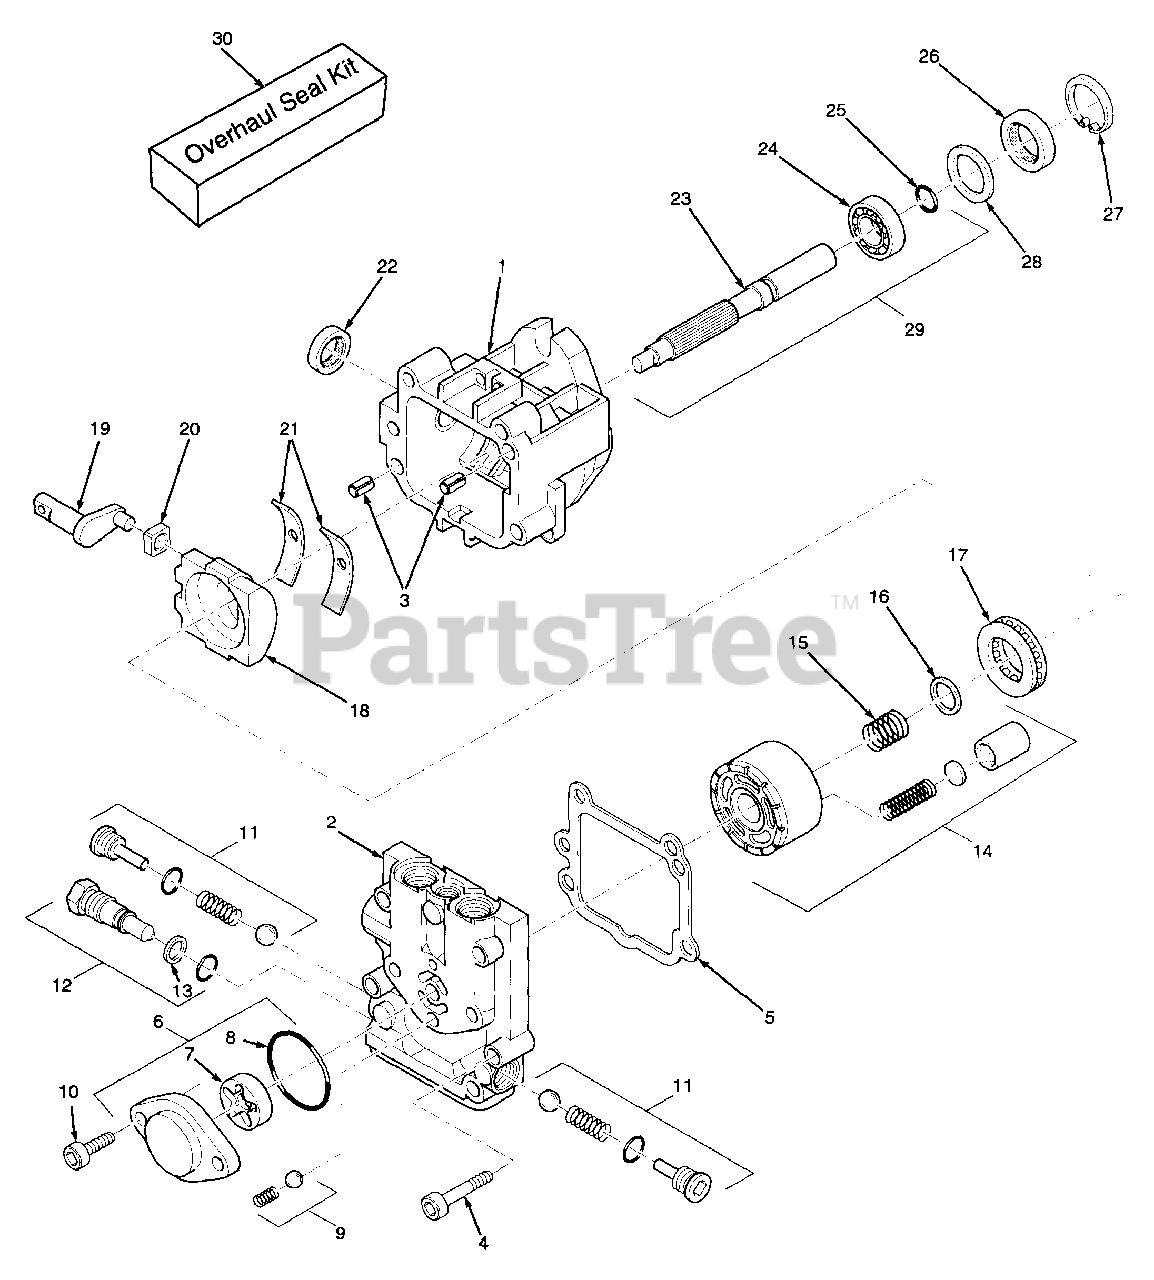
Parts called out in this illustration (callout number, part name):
1	Housing Kit
2	End Cap
3	Straight Headless Pin
4	Socket Head Screw
5	End Cap Gasket
6	Charge Pump Kit
7	Gerotor Assembly
9	Charge Relief Valve Kit
10	Socket Head Screw
11	Check Valve Kit
12	Bypass Valve Kit
13	Backup Ring
14	Cylinder Block Kit
15	Block Spring
16	Block Thrust Washer
17	Roller Thrust Bearing
18	Swash Plate
19	Trunnion Arm
20	Guide Slot
21	Cradle Bearing
23	Pump Shaft
24	Ball Bearing
25	Retaining Ring
27	Retaining Ring
29	Shaft Kit
30	Overhaul Seal Kit
